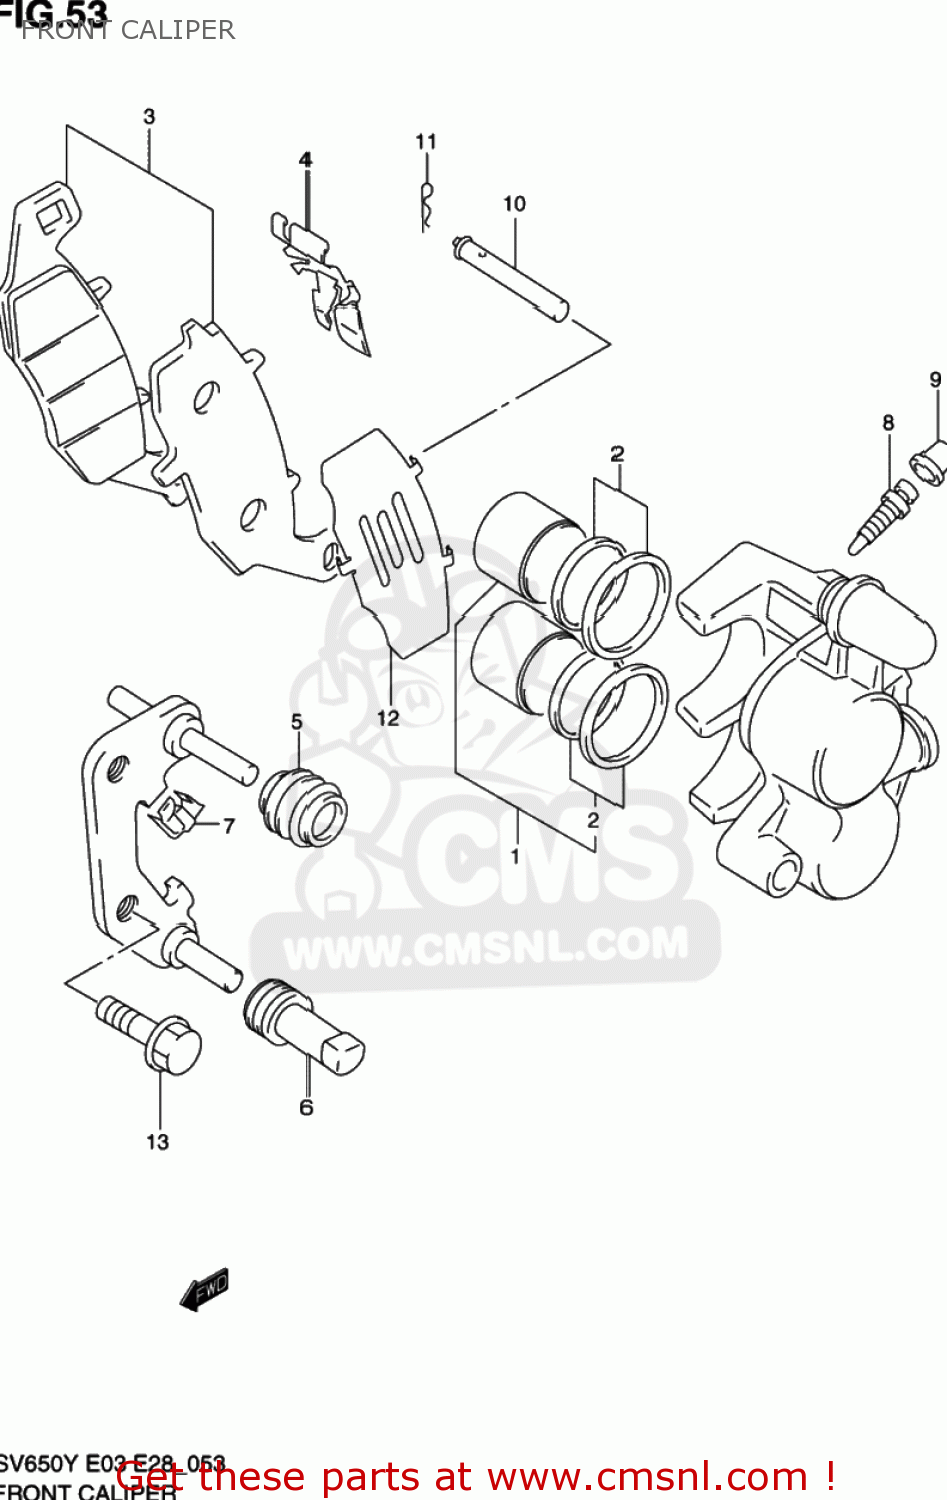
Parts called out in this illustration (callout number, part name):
1	PISTON SET
2	SEAL SET,PISTON
3	PAD SET,R (NAS)
4	SPRING,PAD,R
5	BOOT,AXLE
6	INSULATOR,AXLE
7	GUIDE,PAD
8	BLEEDER
9	CAP,BLEEDER PLUG
10	PIN,PAD
11	CLIP,PAD PIN
12	SHIM,PAD
13	BOLT
